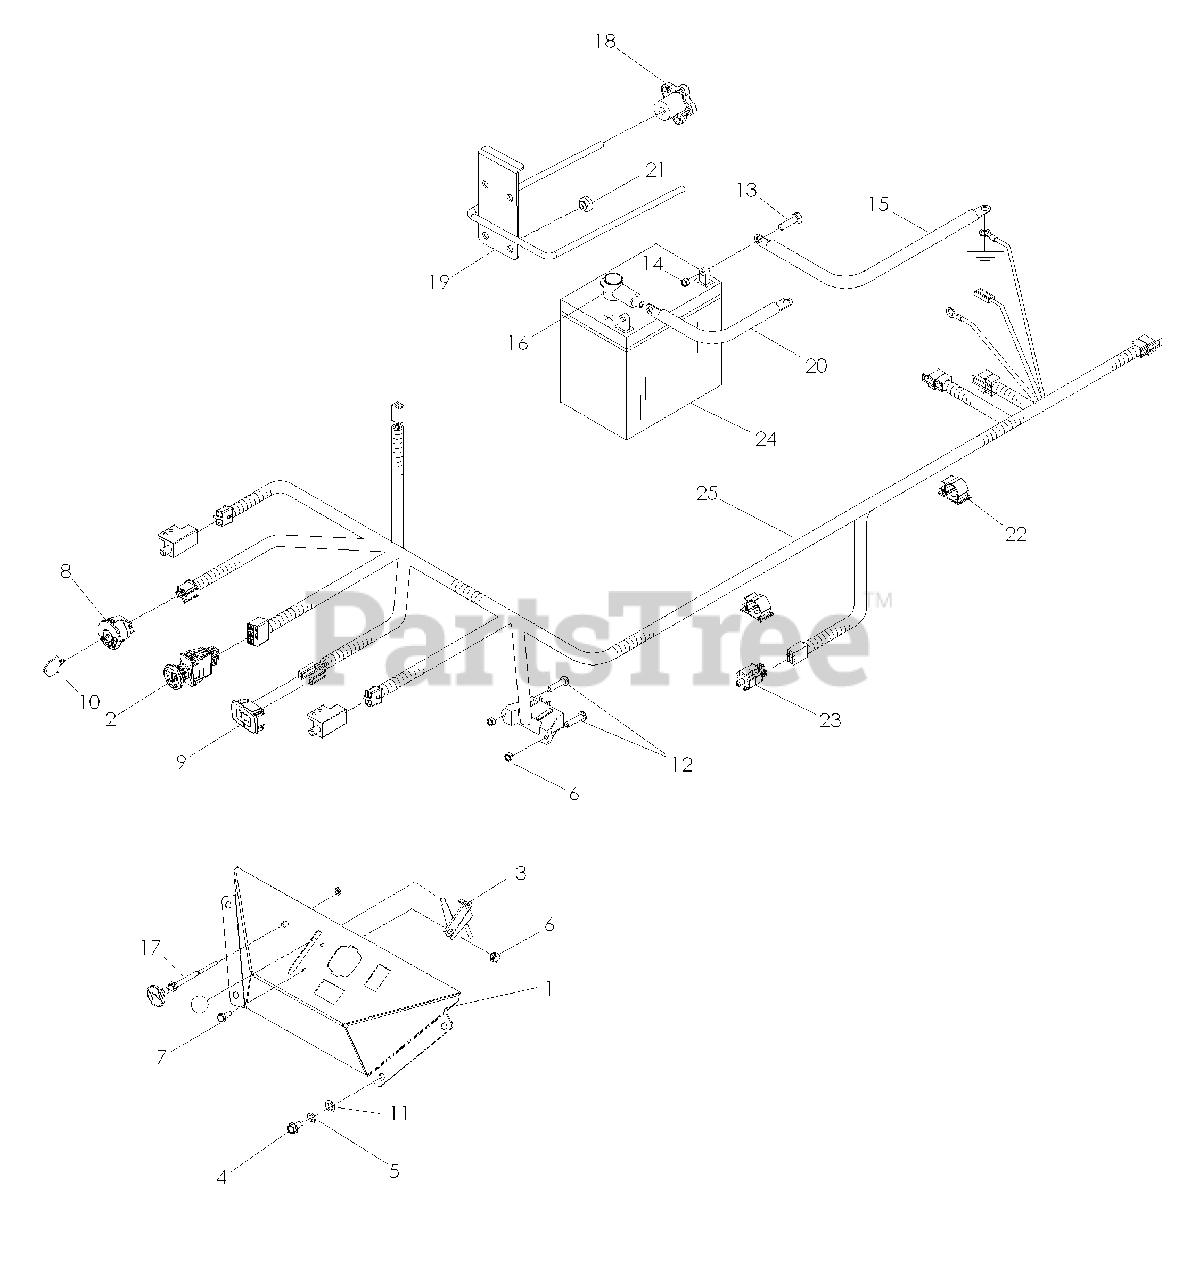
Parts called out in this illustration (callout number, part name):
2	SWITCH, PTO 10 AMP
3	THROTTLE CABLE
4	SCREW 1/4-20 x 5/8
5	WASHER, 1/4 SPLIT LOCK
6	NUT #10-24 HEX NYLOC
7	HCS #10-24 x 1/2
8	IGNITION SWITCH
9	HOUR METER
10	KEY, IGNITION
11	WASHER, 1/4 FLAT
12	SCREW #10-24 x 7/8 SLT HD
13	HCS 5/16-18 x 3/4
14	NUT 5/16-18 HEX NYLOC
15	CABLE, NEGATIVE
16	INSULATOR-BATTERY
17	CHOKE CNTRL / LZ25 ONLY
19	HOLD DOWN, BATTERY
20	CABLE, POSITIVE / LZ25
20	CABLE, POSITIVE / LZ30
22	WIRE CLIP PUSH-MOUNT
23	SWITCH, BRAKE
24	BATTERY, DRY
